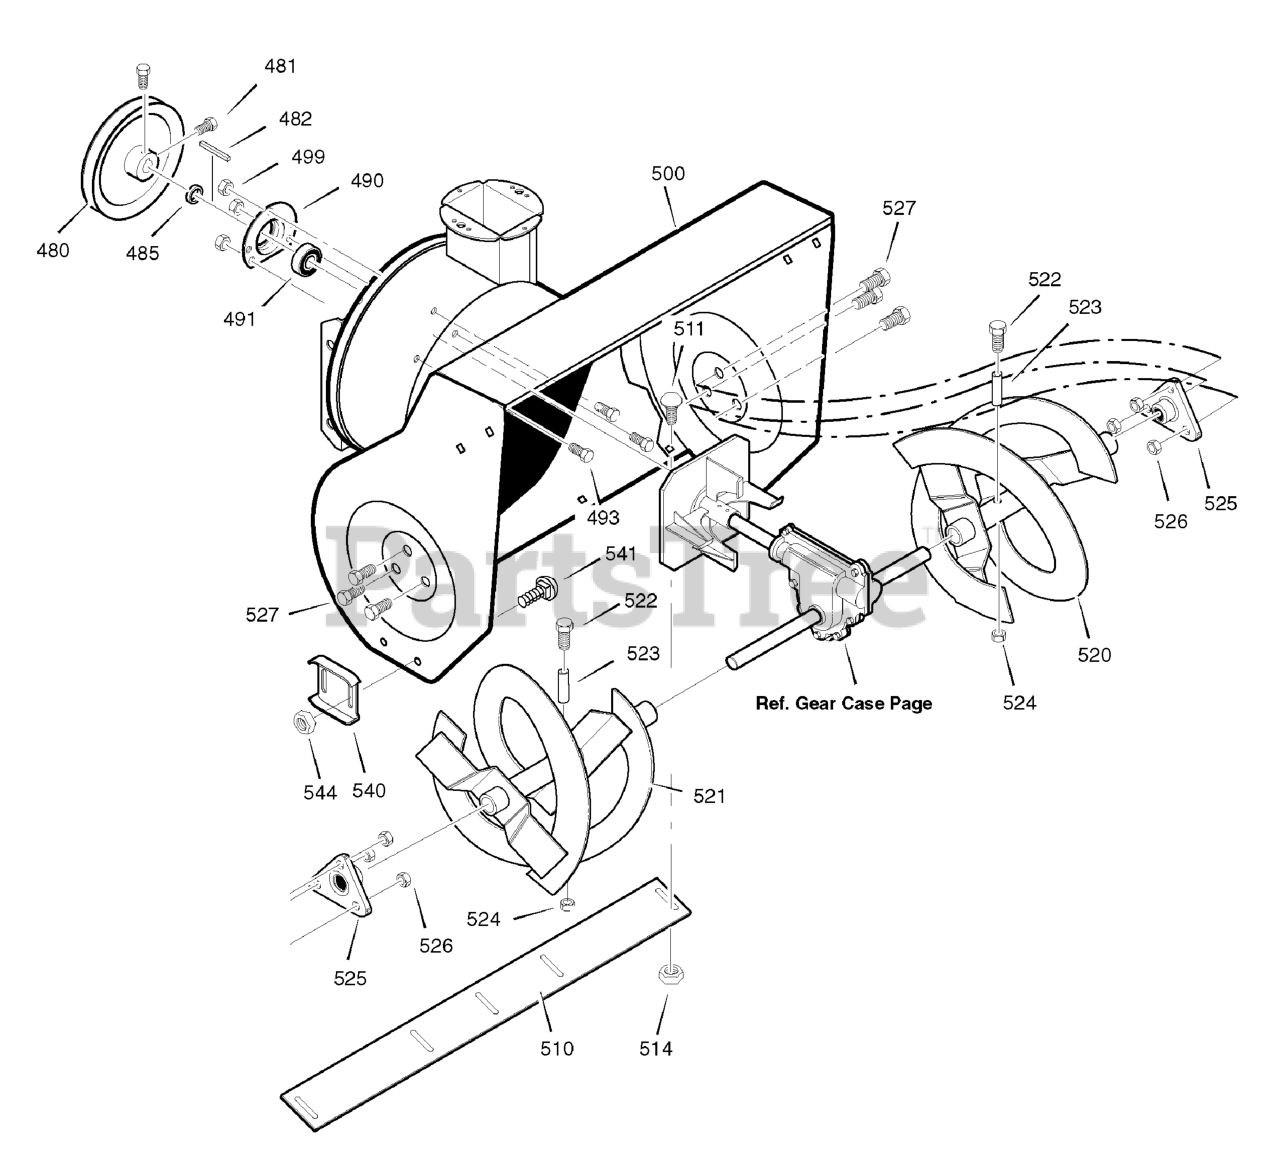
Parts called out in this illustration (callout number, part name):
480	PULLEY, 4L 6.12X .67
481	SCREW, 5/16-18 x 0.63
482	KEY, SQUARE 3/16 X 3/4
485	SPACER, FRICTION PULLEY
490	RETAINER, BALL BRNG
491	BEARING, BALL
493	BOLT, HEX 5/16-18X .50
499	NUT, 5/16-18 HEXWDFLLK
500	HOUSING, ASSY
510	BLADE, SCRAPER
511	BOLT, 1/4-20X.75
514	NUT, 1/4-20
520	AUGER, ASSY, LH
521	AUGER, ASSY, RH
522	SCREW, 1/4-20X1.75
523	SPACER, SLEEVE
524	NUT, 1/4-20
525	BEARING,FLANGE
526	NUT, 5/16-18
527	SCREW, 5/16-18 x 0.75
540	SKID, HEIGHT ADJUST
541	BOLT, 5/16-18 X .75
544	NUT, 5/16-18
